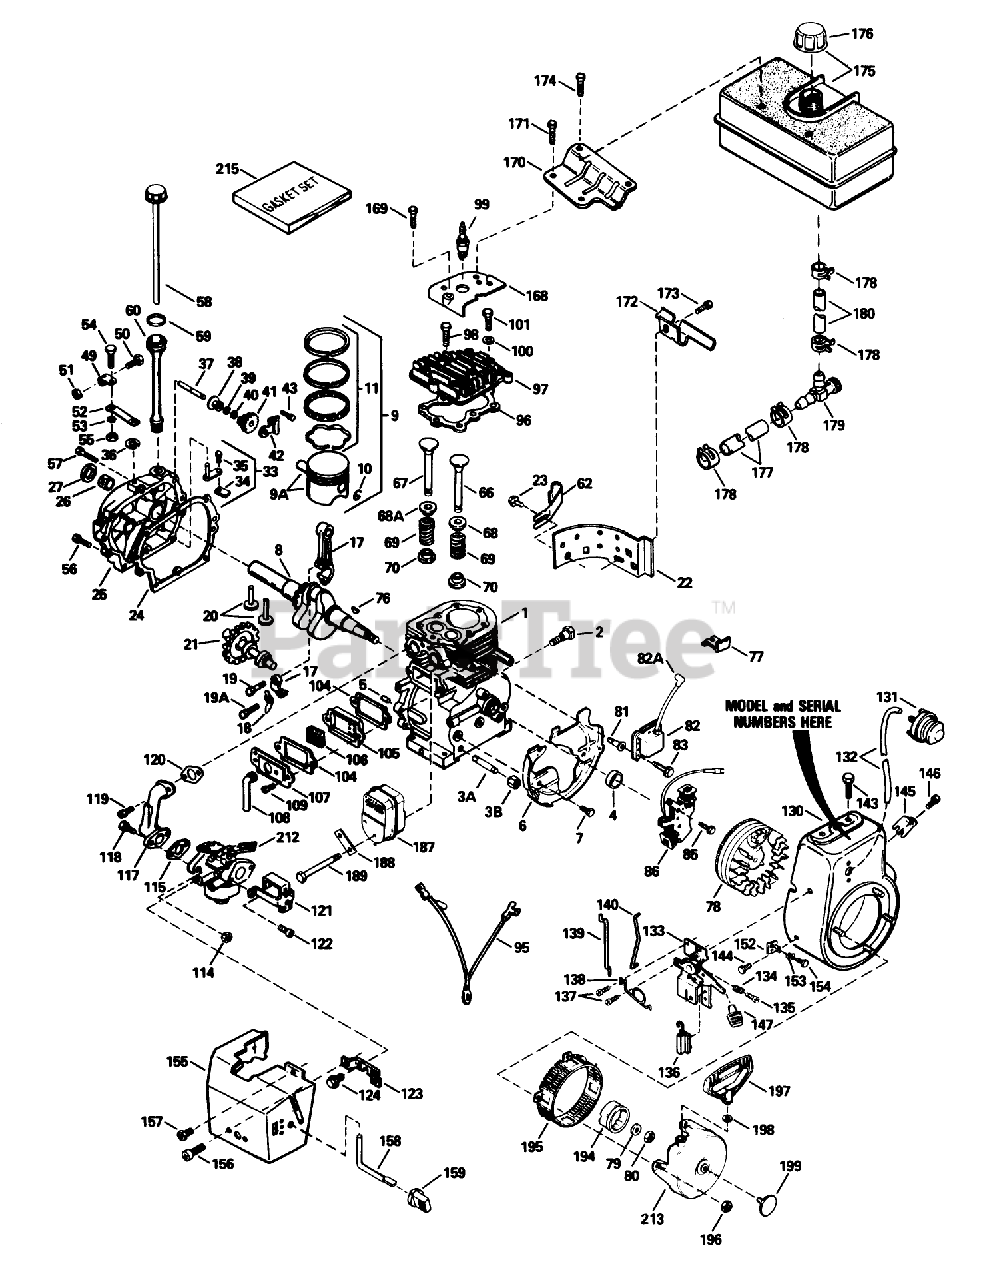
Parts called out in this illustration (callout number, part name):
1	Cylinder Asm (Includes 2, 20, 72)
2	Screw (1/4-20x1/2)
3A	Nipple-Pipe
3B	Cap-Pipe
4	Seal-Oil
5	Pin-Dowel
6	Baffle-Blower Housing
7	Screw (1/4-20x19/32)
8	Crankshaft
9	Piston, Pin Ring Assy.(Std.) (Incl. Ref. #24A, 25 26)
9A	Piston Pin Assy. (Std.) (Incl. Ref. #26)
11	Ring Set (Std.)
17	Rod Assy., Connecting (Incl. Ref. #28 28A)
18	Dipper-Oil
19	Bolt-Rod
19A	Bolt-Rod
20	Lifter-Valve
21	Camshaft (MCR)
22	Extension-Housing, Blower
23	Screw
24	Cylinder Cover Gasket
25	Cover-Cylinder (Includes 71, 75, 80)
26	2025A77 WIZARD ROTA
27	Seal-Oil
33	Rod, Governor (Incl. Nos.62 63)
34	Yoke-Governor
35	Screw (6-40x5/16)
36	Ring-Retaining
37	Shaft-Governor
38	Spool-Governor
39	Washer
40	Ring-Retaining
41	Gear Assy., Governor (Incl. Ref. #45)
42	Bracket-Gear, Governor
43	Screw (10-24x1/2)
49	Clamp-Lever, Governor
50	Screw
51	Nut-Lock
52	Lever-Governor
53	Washer-Lock
54	Screw
55	Nut-Lock
56	Screw (1/4-20x1-11/16)
57	Screw (1/4-20x1-3/16)
58	Dipstick
59	O-Ring
60	Tube-Fill, Oil
62	Clip-Tube, Fill
66	Valve, Exhaust (Standard)(Incl. No. 9)
67	Valve, Intake (Std.) (Incl. Ref. #58)
68	Cap-Spring, Valve
68A	Seal-Intake Valve
69	Spring-Valve
70	Keeper-Spring, Valve
76	Key-Flywheel
77	Clip-Wire
78	Flywheel ASM
79	Washer-Belleville
80	Nut-Flywheel
82	Solid State ASM
82A	Cover-Spark Plug
83	Screw
85	Screw (1/4-20 x 3/4)
86	Coil-Alternator, 18 Watt (Includes 323)
95	Ground Wire
96	Gasket-Cylinder Head
97	Head Cylinder
98	Screw (5/16-18x1-1/2)
99	Spark Plug-Resistor (R J19 L M)
100	Washer-Flat
101	Screw (5/16-18x1-25/32)
104	Gasket-Cover, Valve
105	Body-Breather
106	Element-Breather
107	Cover-Valve
108	Tube-Breather
109	Screw
114	Nut and Lock Washer (1/4-28)
115	Gasket-Carburetor To Intake Pipe
117	Pipe-Intake
118	Screw (1/4-28x1)
119	Screw (T-30, 5/16-18x1-3/32)
120	Gasket-Pipe, Intake
121	Bracket-Choke
122	Screw (10-32 x 1/2)
123	Bracket-Carburetor
124	Screw (8-32x27/64)
130	Housing-Blower
131	Primer-Asm
132	Line-Primer
133	Bracket-Control (Includes 19, 203, 204, 206)
134	Spring-Compression
135	Screw
136	Terminal
137	Screw (10-32 x 1/2)
138	Spring-Throttle
139	Link-Governor
140	Link-Throttle
143	Screw (5/16-18x3/4)
144	Screw
145	Screw
146	Screw (8-32 x 3/8)
147	Knob-Control
152	Bracket
153	Grommet
154	Screw (8-32 x 3/8)
155	Cover-Carburetor
156	Screw (10-32 x 3/8)
157	Screw (10-32x1/2)
158	Rod-Choke
159	Knob-Control
168	Cover-Cylinder Head
169	Screw (1/2-20x5/8)
170	Bracket-Tank, Fuel (Black)
171	Screw
172	Bracket-Tank, Fuel
173	Screw (1/4-20x19/32)
174	Screw (1/4-15x7/8)
175	Tank-Fuel (Includes 292, 301)
176	Cap-Fuel
177	Line-Fuel
178	Clamp-Line, Fuel
179	Valve-Shut Off
180	Line-Fuel (8.62)
187	Muffler
188	62513 SNWTHWR W/284
189	Screw
194	Cup-Starter
195	Screen-Starter
196	Nut and Lock Washer (1/4-28)
197	Handle-Starter, Mitten Grip
198	Washer
199	Plug Starter
212	Carburetor (Incl. Ref. #184)
213	Starter-Rewind
215	Gasket Set (Incl. items marked *)
